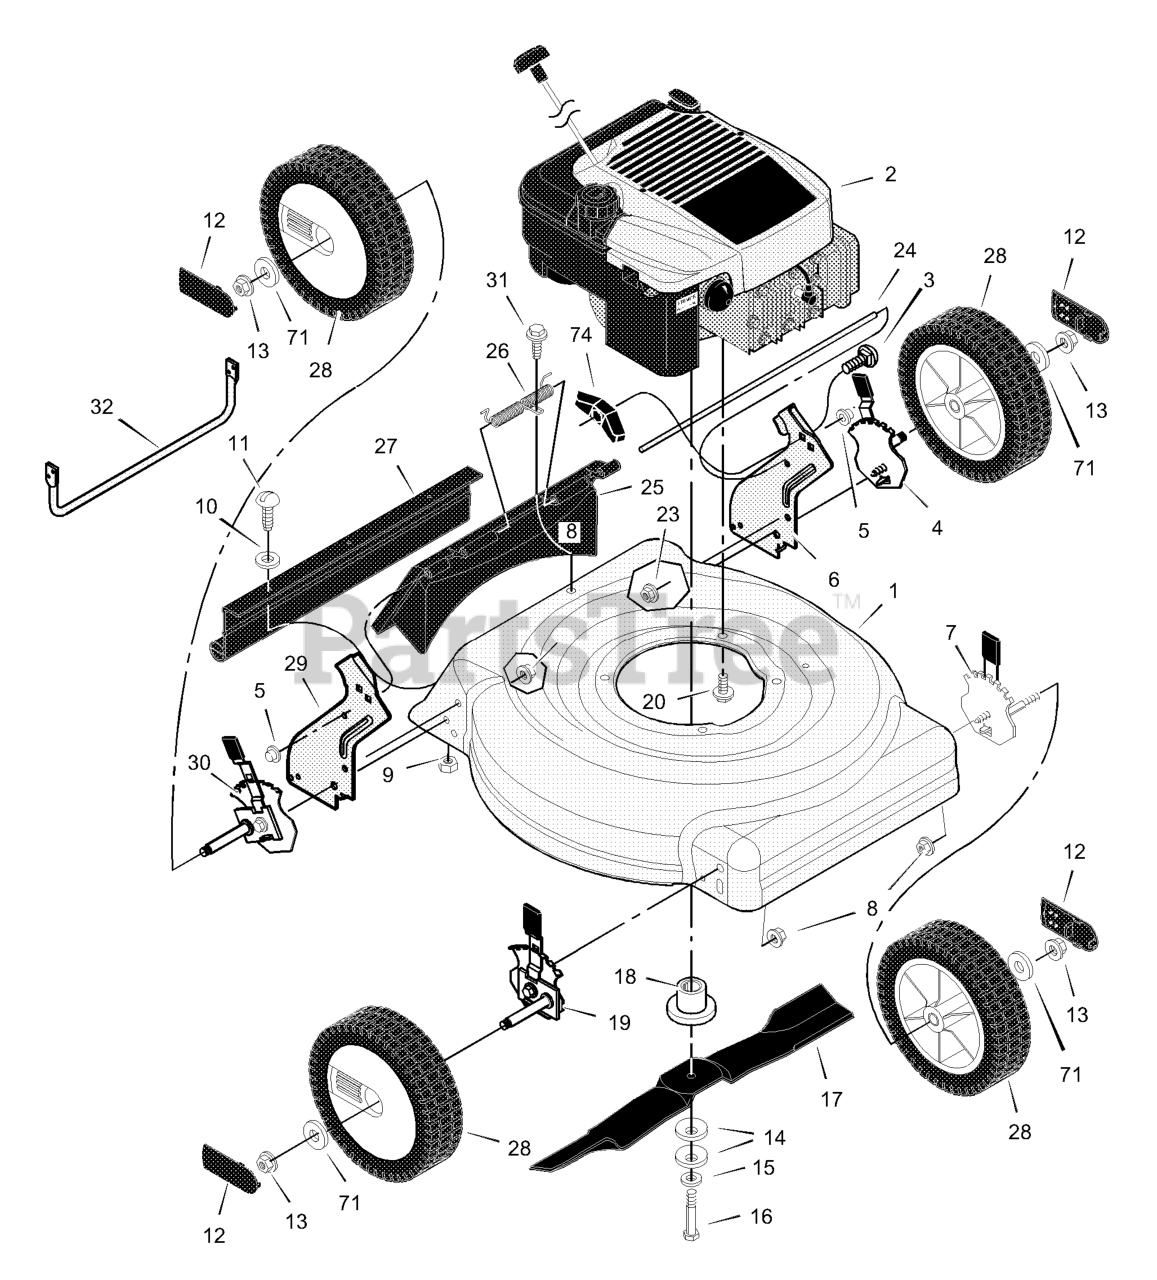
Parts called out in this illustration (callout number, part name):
1	Housing
2	Engine
3	Bolt, Carriage
4	Adjuster, Left Rear Height
5	Push On Cap
6	Bracket, Left Handle
7	Adjuster, Left Front Height
8	Nut, Flange
9	Nut, Hex
10	Washer
12	Hub Cap
13	Nut, Flange
14	Washer, Belleville
18	Adapter, Blade
19	Adjuster, Right Front Height
20	Bolt, Engine
23	Nut, Flange
24	Rod, Pivot
25	Door, Rear
26	Spring
27	Guard, Rear
29	Bracket, Right Handle
30	Adjuster, Right Rear Height
32	Guard, Rear
